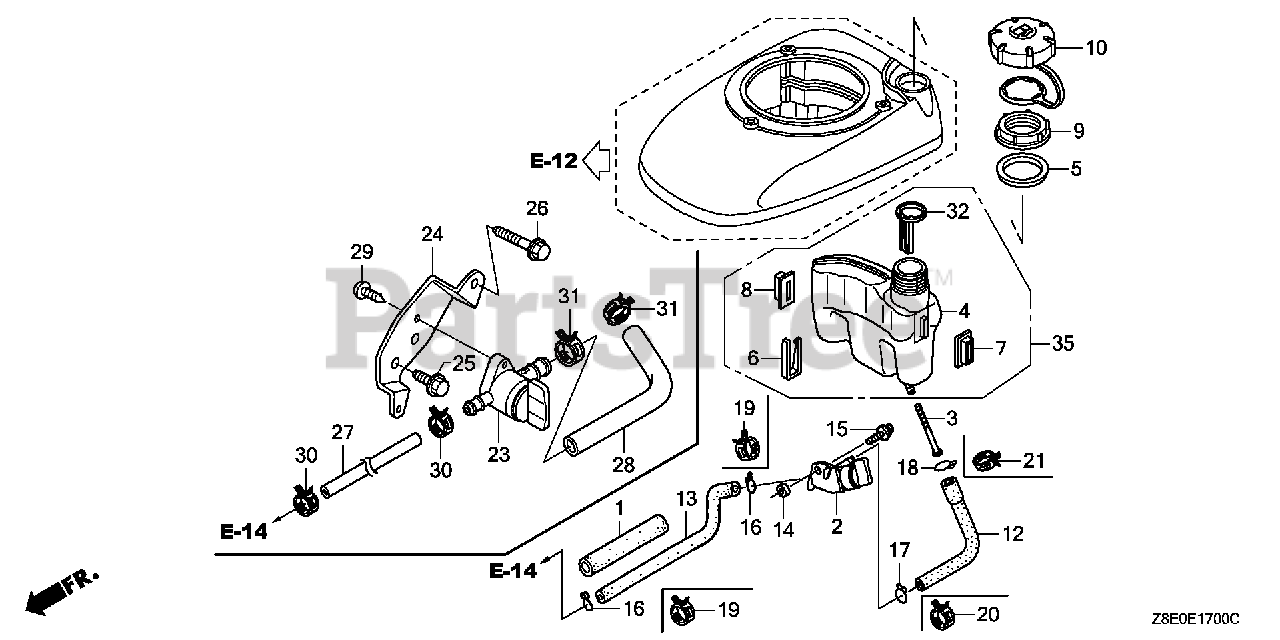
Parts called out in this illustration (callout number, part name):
3	FILTER, FUEL
4	TANK, FUEL
5	SEAL, FUEL FILLER NECK
6	CLIP, TANK MOUNTING
7	RUBBER A, TANK MOUNTING
8	RUBBER B, TANK MOUNTING
9	NUT, TANK MOUNTING
10	CAP ASSY., FUEL TANK
23	PETCOCK ASSY.
24	STAY, PETCOCK
25	BOLT, FLANGE (6X12) (CT200)
26	BOLT, FLANGE (6X28) (CT200)
27	TUBE, FUEL (4.5X110) (FKM)
28	TUBE, FUEL (7.3X160) (FKM)
29	SCREW, TAPPING (5X12) (PO)
30	CLAMP, TUBE (D8)
31	CLAMP, TUBE (D12)
32	GAUGE, FUEL LEVEL
35	TANK KIT, FUEL
